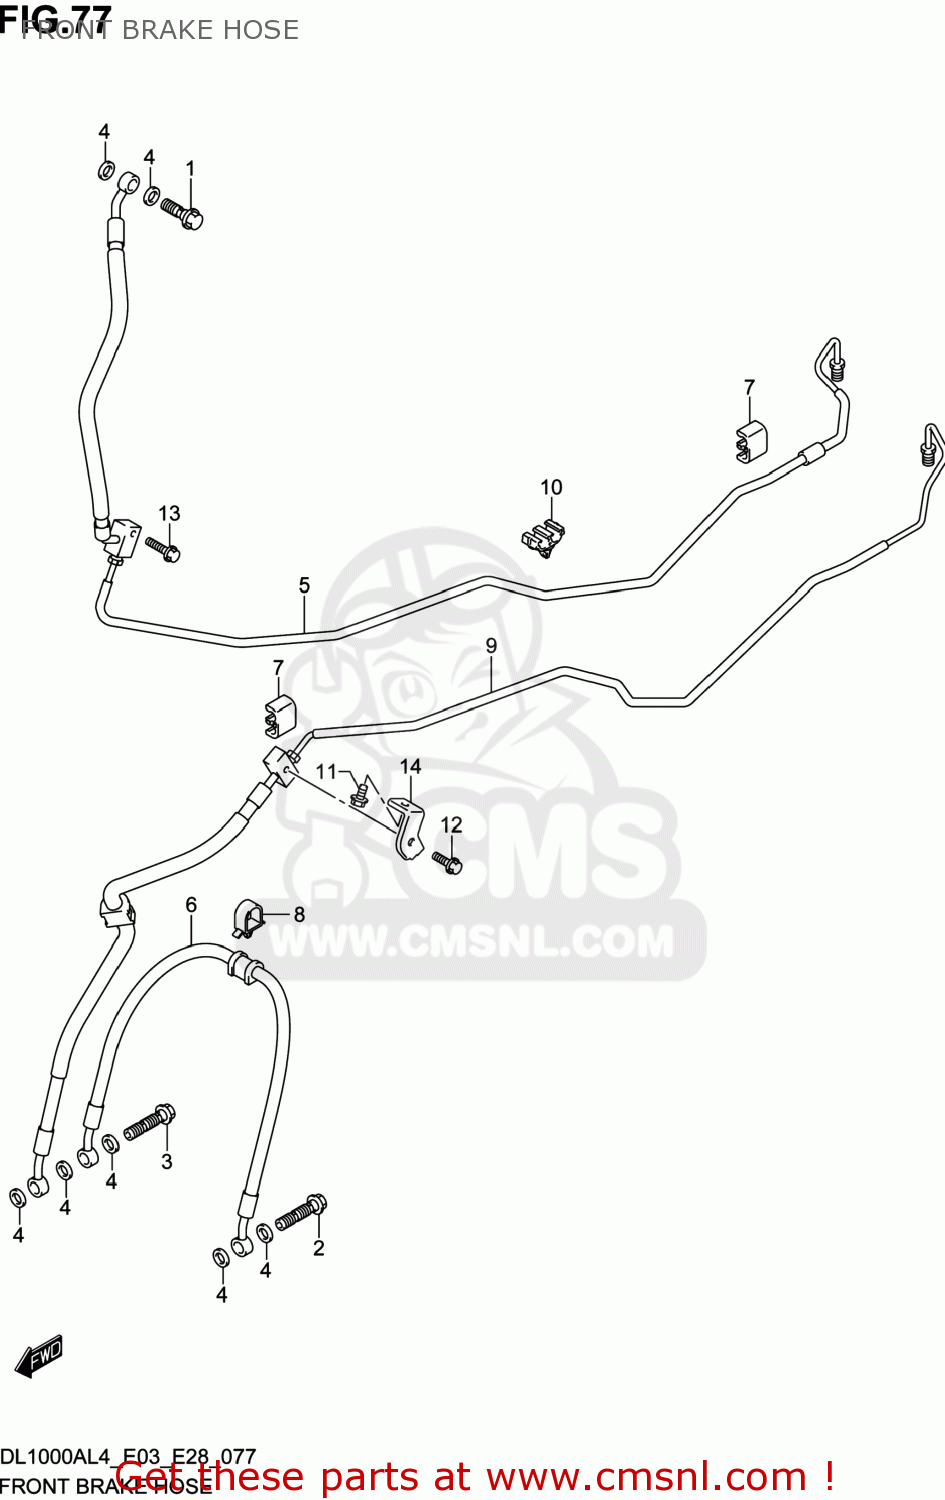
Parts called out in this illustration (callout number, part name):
1	BOLT UNION
2	BOLT UNION
3	BOLT UNION
4	WASHER(10X15X1.5)
5	HOSE ASSY,FR MASTER TO UNIT
6	HOSE,FR CLPR TO CLPR
7	CLAMP
8	CLAMP
9	HOSE ASSY,FR UNIT TO CLPR
10	CLAMP
11	BOLT
12	BOLT
13	BOLT
14	CLAMP,FR BRAKE HOSE NO.1
